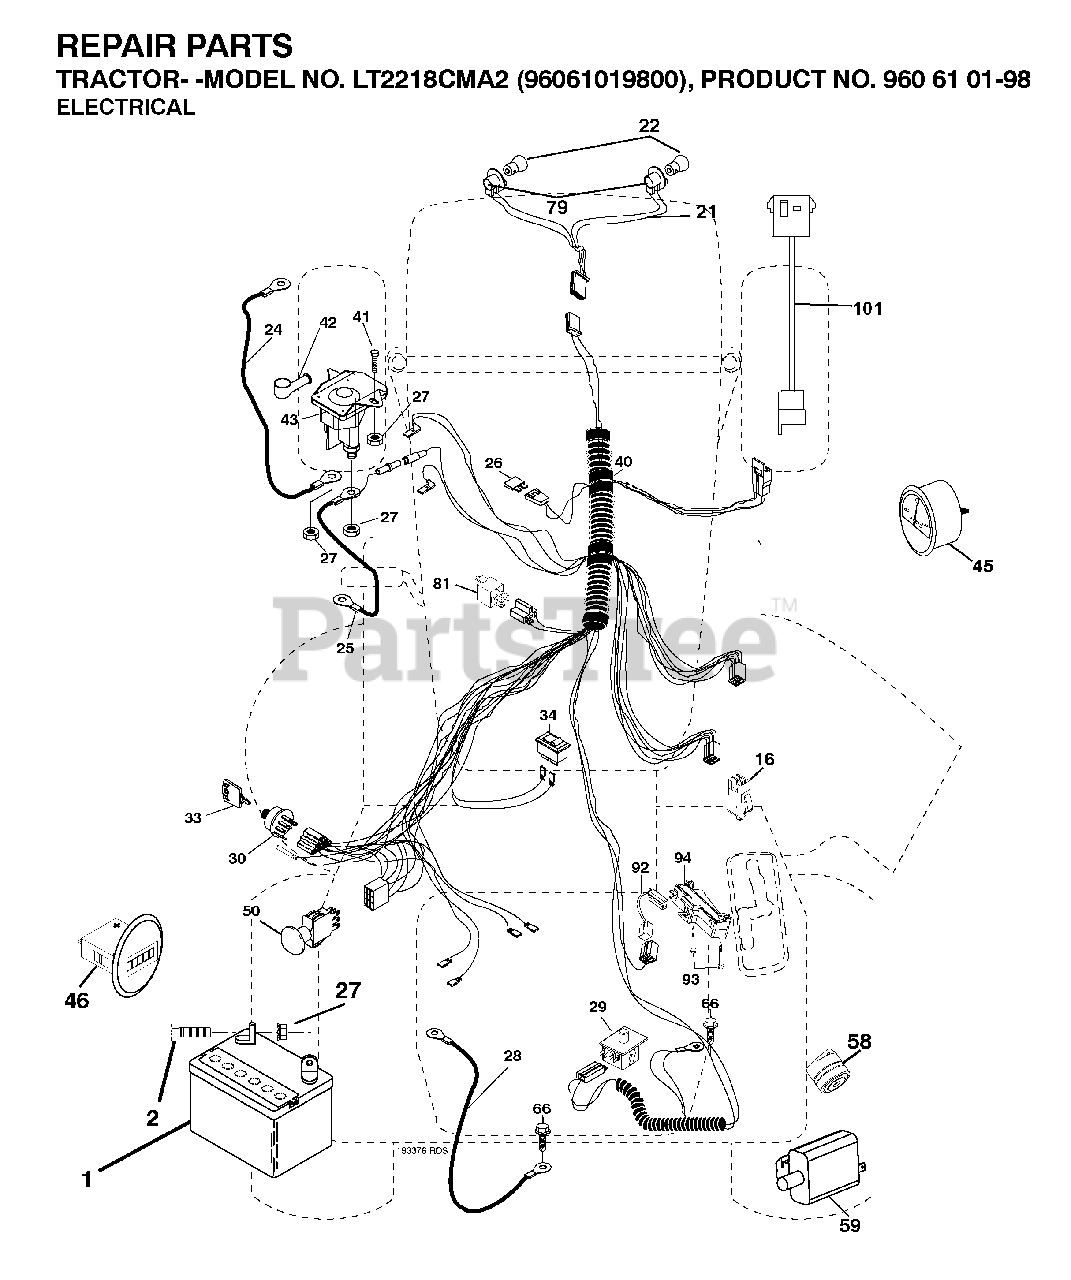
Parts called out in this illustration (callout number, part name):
1	BATTERY 12V .35 AMP
16	SWITCH INTERLOOK PUSH-IN
21	HARNESS.W/LIGHT SOCKET
22	LIGHTBULB
24	BATTERY CABLE GT
25	CABLE BATTERY
26	FUSE 20AMP
27	NUT
28	CABLE GROUND
29	SWITCH.SEAT.DP W/RAMPS
30	SWITCH.IGN.DELTA.W.LGH.ROS
33	KEY MLD GEN DELTA
34	SWITCH LT
42	TERMINAL COVER
43	SOLENOID.W/BRASS.PLUNG
46	HOURMETER SNAP-IN
50	PTO SWITCH
58	BUZZER
79	BULB HOLDER ASM.
81	RELAY.ASSY.T
92	HARNESS.PIGTAIL.CONSLE
93	SCREW.PLASTITE
94	MODULE.REVERSE.ROS
101	PIGTAIL.MATNLK.NEW.HAR
